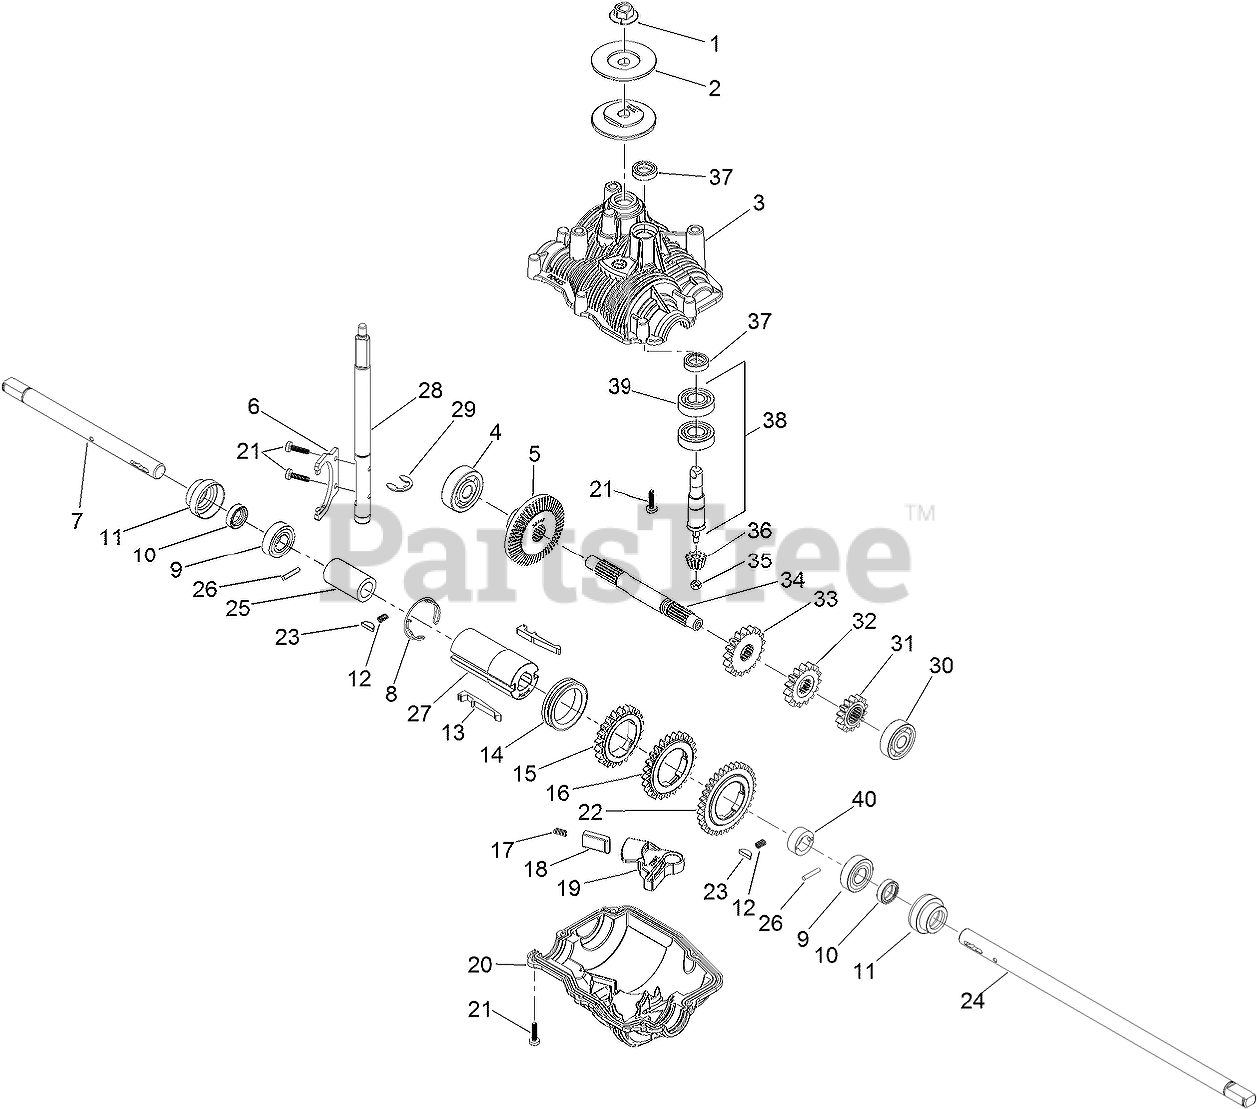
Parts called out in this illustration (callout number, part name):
1	NUT-FLANGE
2	FLANGE-PULLEY
3	CASE-UPPER, TRANSMISSION
4	BEARING-BALL
5	GEAR-BEVEL, 53 TOOTH
6	FORK-SHIFT
7	SHAFT-OUTPUT, SHORT
8	SPRING-RETAINING
9	BEARING-BALL
11	BUSHING-SHAFT, OUTPUT
12	SPRING
13	KEY-SHIFT
14	RING-SHIFT
15	GEAR-OUTPUT, 22 TOOTH
16	GEAR-OUTPUT, 25 TOOTH
17	SPRING-INDEXING, SHIFTER
18	PIN-INDEXING, SHIFTER
19	LEVER-INDEXING, SHIFTER
20	CASE-LOWER, TRANSMISSION
22	GEAR-OUTPUT, 32 TOOTH
24	SHAFT-OUTPUT, LONG
25	SPACER-LONG
27	HUB-GEAR, OUTPUT
28	SHAFT-SHIFT
29	RING-RETAINING
30	BEARING-BALL
31	GEAR-INTERMEDIATE, 14 TOOTH
32	GEAR-INTERMEDIATE, 15 TOOTH
33	GEAR-INTERMEDIATE, 17 TOOTH
34	SHAFT-INTERMEDIATE
35	NUT-SHAFT, INPUT
36	GEAR-BEVEL, 12 TOOTH
38	SHAFT-INPUT
39	BEARING-BALL
40	SPACER-SHORT
